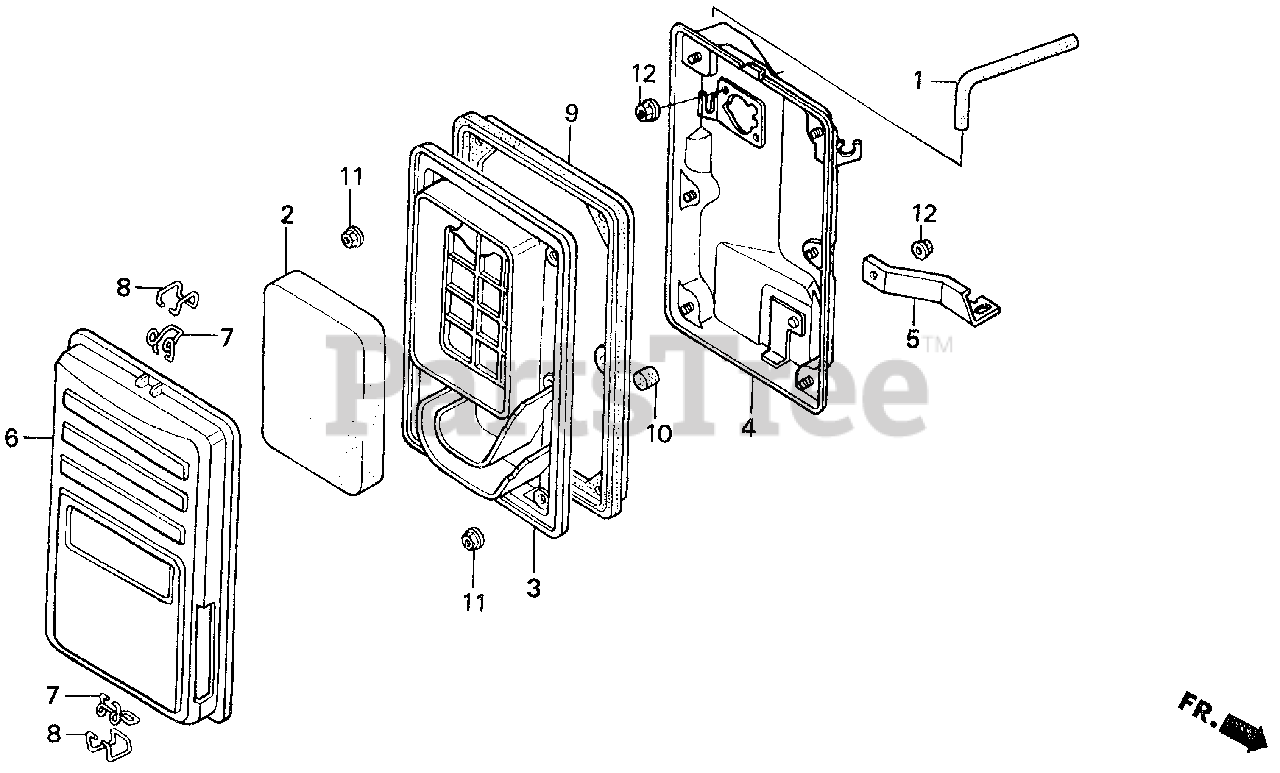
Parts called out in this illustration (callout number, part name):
1	TUBE, BREATHER
2	ELEMENT, AIR CLEANER
3	SEPARATOR, AIR CLEANER
4	HOUSING, AIR CLEANER
5	STAY, AIR CLEANER
6	COVER, AIR CLEANER
7	CLIP A, AIR CLEANER WIRE
8	CLIP B, AIR CLEANER WIRE
9	SEAL, AIR CLEANER
10	FILTER, DRAIN TUBE
11	NUT, FLANGE (5MM)
12	NUT, FLANGE (6MM)
